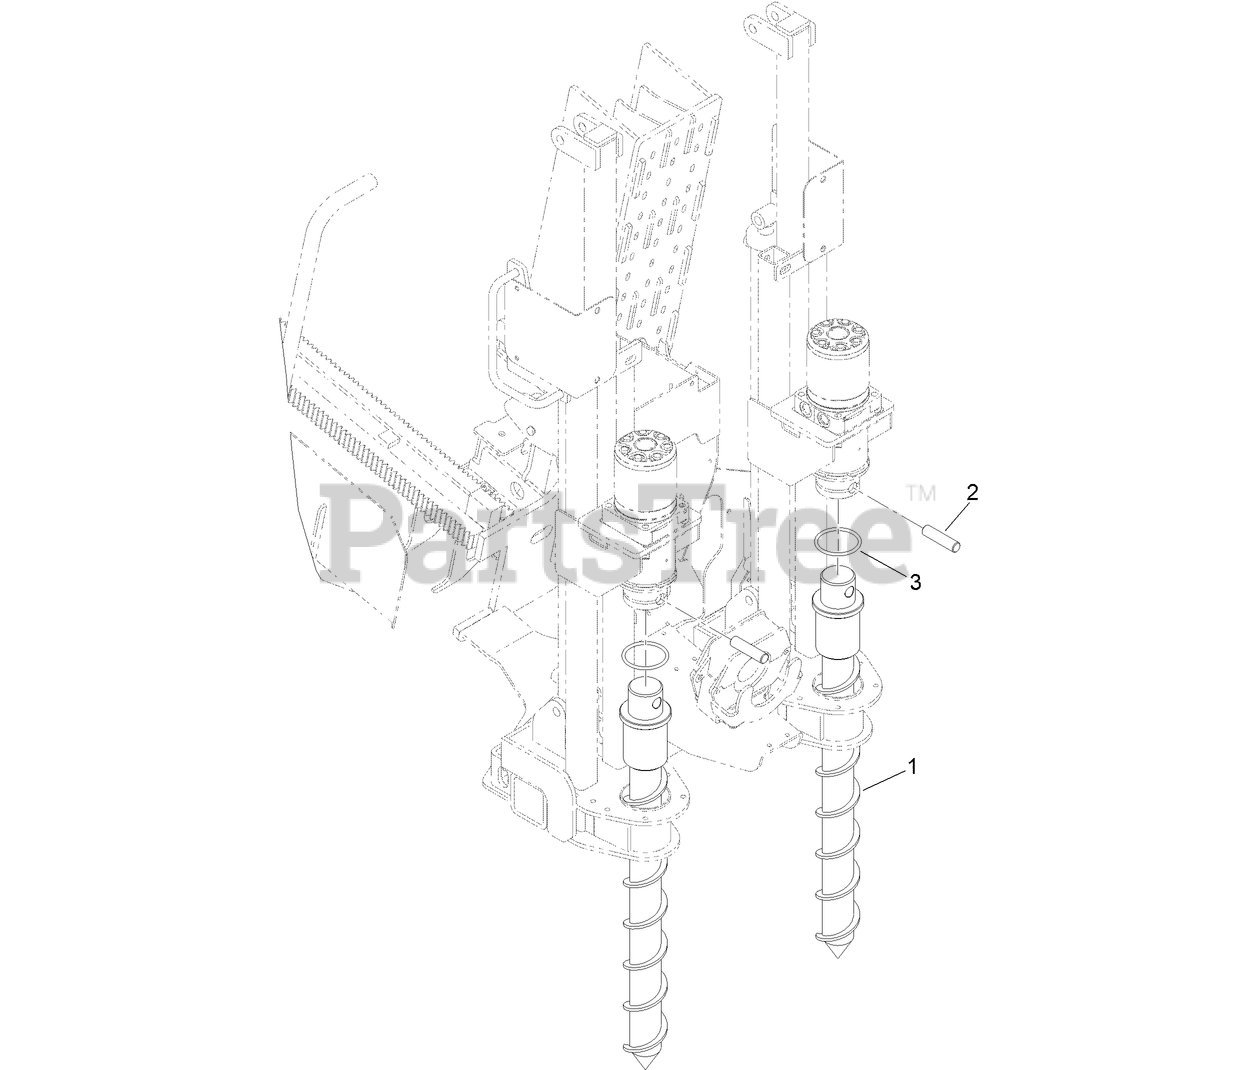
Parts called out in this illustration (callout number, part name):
1	STAKE-DIRT, HD
2	PIN-STAKE
3	O-RING
